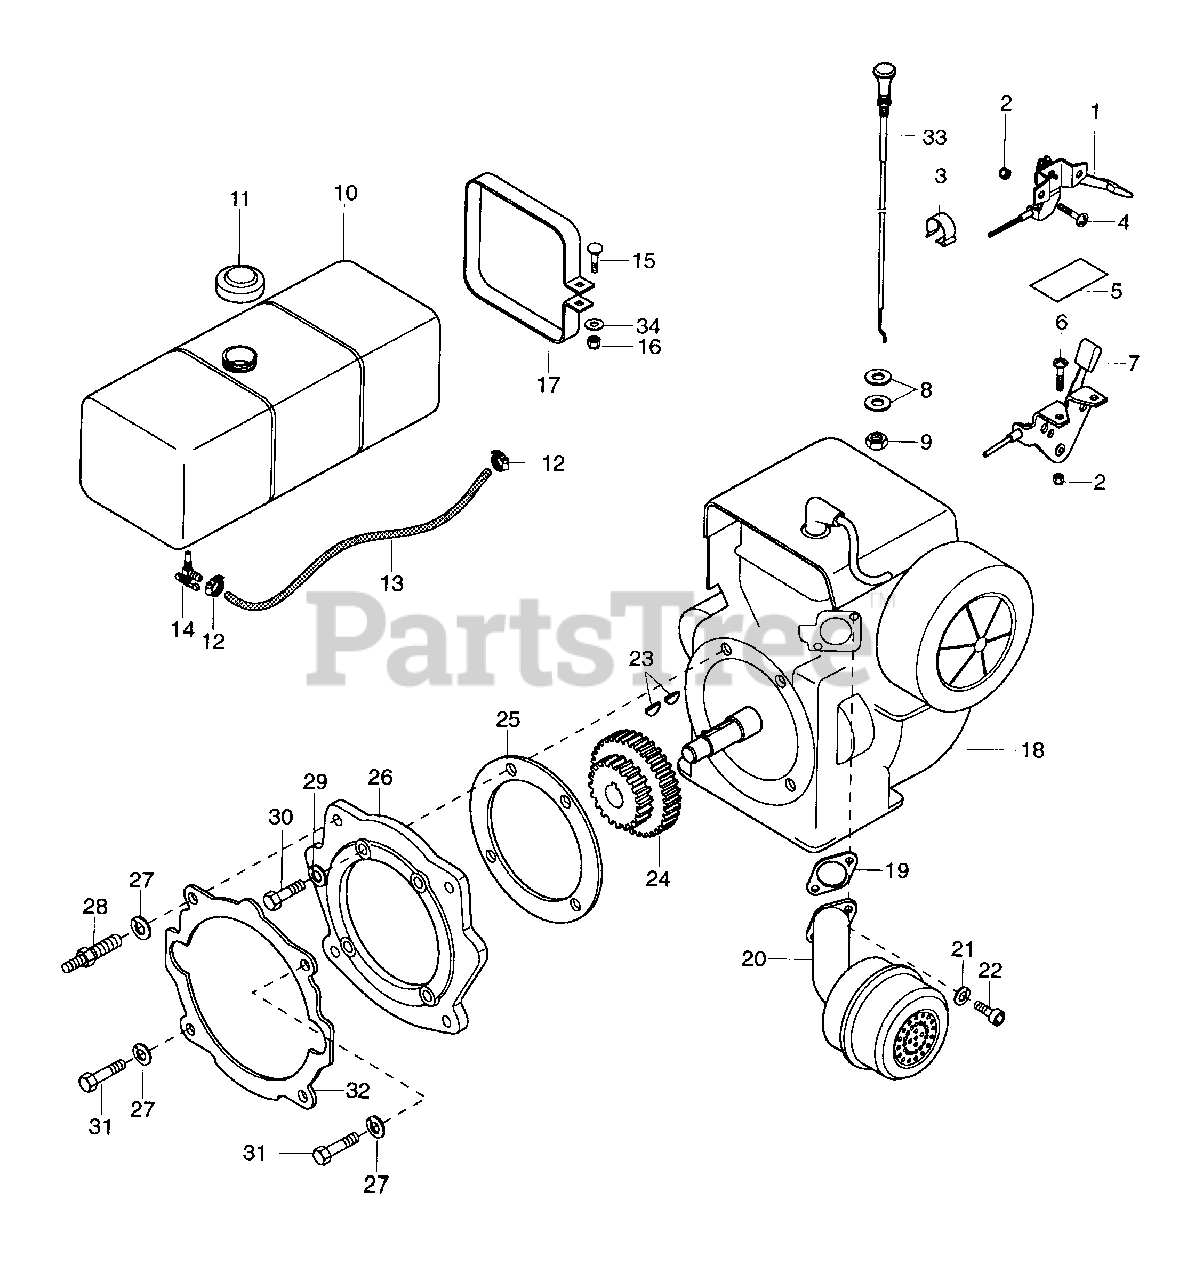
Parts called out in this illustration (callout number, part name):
1	LVR, CONTROL(8 HP ELECTRIC)
1	LVR, THRTL CNTRL(8 HP MAN)
2	NUT-LK 10-24 NY PL(8HP)
2	NUT-LK 10-24 NY PL(12 HP)
3	CLAMP
4	SCR-MCH 10-24 X 1.50 PHDCR
5	DECAL, THROTTLE
6	SCR-MCH 10-24 X .50 PHD(12 HP)
7	LVR, THROTTLE CONTROL(12 HP)
7	LVR, CONTROL
8	WSHR-FL-STL .406 X .812 X .065 PL(12 HP)
9	NUT JAM .375-24 PL(12 HP)
10	ASM, FUEL TANK(12 HP)
11	CAP, GAS TANK(12 HP)
12	HOSE CLAMP(12 HP)
13	GAS LINE-BULK(12 HP)
14	VLV, AND STRAINER(12 HP)
15	BLT-RDHDSQNK .25-20 X 1.75(12 HP)
16	NUT-LK-NYL .250-20 PL(12 HP)
17	STRAP, FUEL TANK(12 HP)
18	ENG, 12 HP ELECT.
18	ENG, 12 HP MAN
18	ENG, 8 HP ELECT.
18	ENG, 8 HP RECOIL
19	GASKET, EXHAUST(12 HP)
20	MUFFLER, 12 HP(12 HP)
21	WSHR-LOCK .313 X .078 PL(12 HP)
22	SCR-CAP .31-18 X .75 S/HD(12 HP)
23	KEY, WDRF .16 X .63 HRD # 6
24	GR, 10/12 DP 21/30 TEETH
25	GSKT, ENGINE TO ADAPTER(12 HP)
25	GSKT, ENGINE TO ADAPTER(8 HP)
26	ADPT, ENGINE(12 HP)
26	ADPT, ENGINE(8 HP)
27	WSHR-LOCK .438 X .133 HVY
28	STUD
29	WSHR-LOCK .375 X .115 HVY PL
30	BLT-HEX .38-16 X 1.00 PL GR 5
31	BLT-HEX BLT-HEX .44-14 X 1.50
32	GSKT, CHASSIS TO ADAPTER
33	WSHR-FL-STL .469 X .938 X .065
34	LVR, CHOKE CONTROL(12 HP)
35	WSHR-FL-STL .281 X .62 X .065 PL
